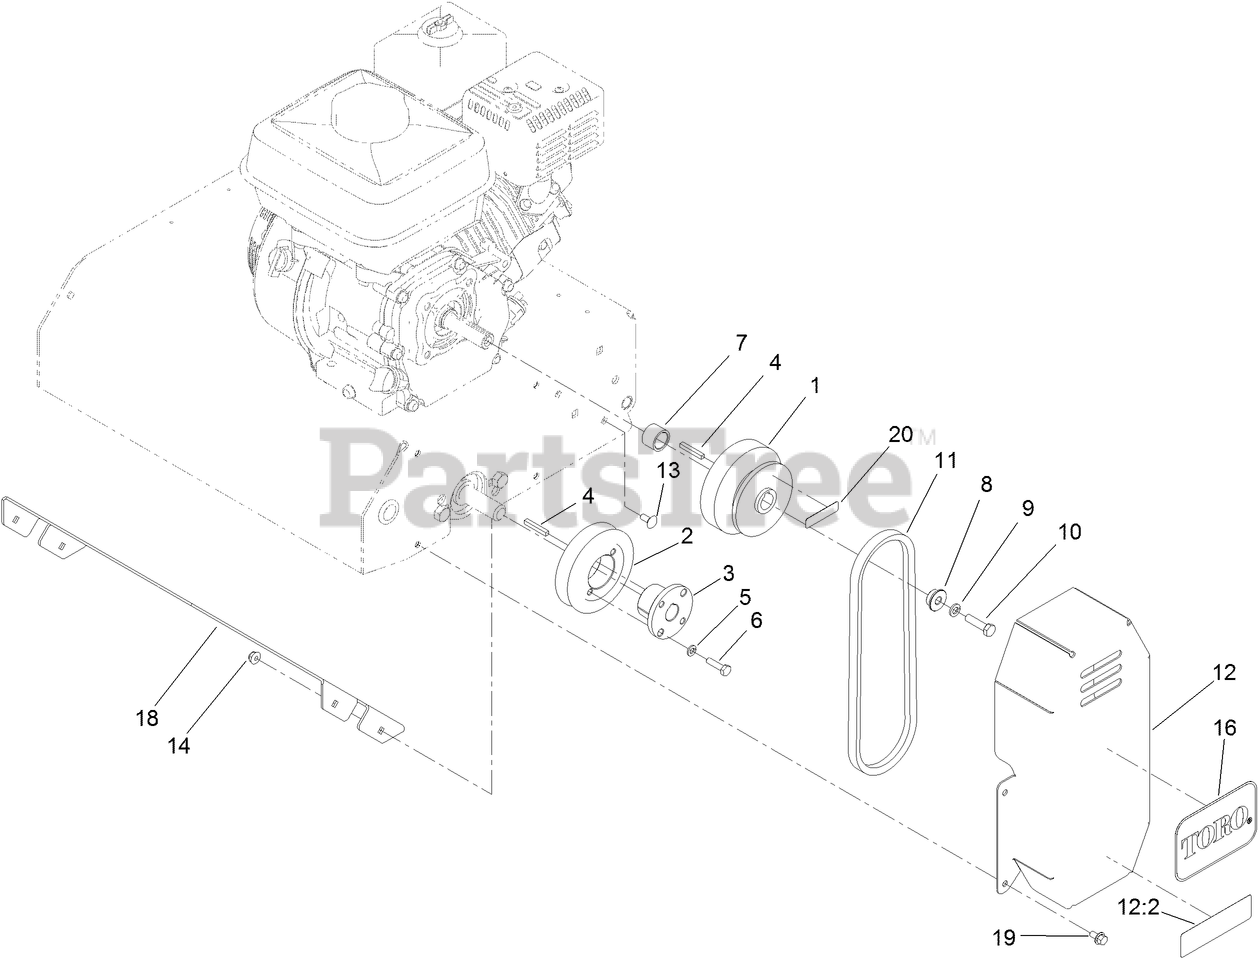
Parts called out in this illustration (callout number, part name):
1	CLUTCH-CENTRIFUGAL
2	SHEAVE-TAPER LOCK
3	BUSHING-TAPER LOCK
4	KEY-SQUARE
5	WASHER-LOCK
6	SCREW-HH
7	SPACER
8	BUSHING
9	WASHER-LOCK
10	SCREW-HH
11	V-BELT
12	BELT GUARD ASM
12:2	DECAL-DANGER
13	SCREW-CARR
14	NUT-HF
16	DECAL
18	BAFFLE-DEFLECTOR
19	SCREW-HHF
20	DECAL-WARNING
